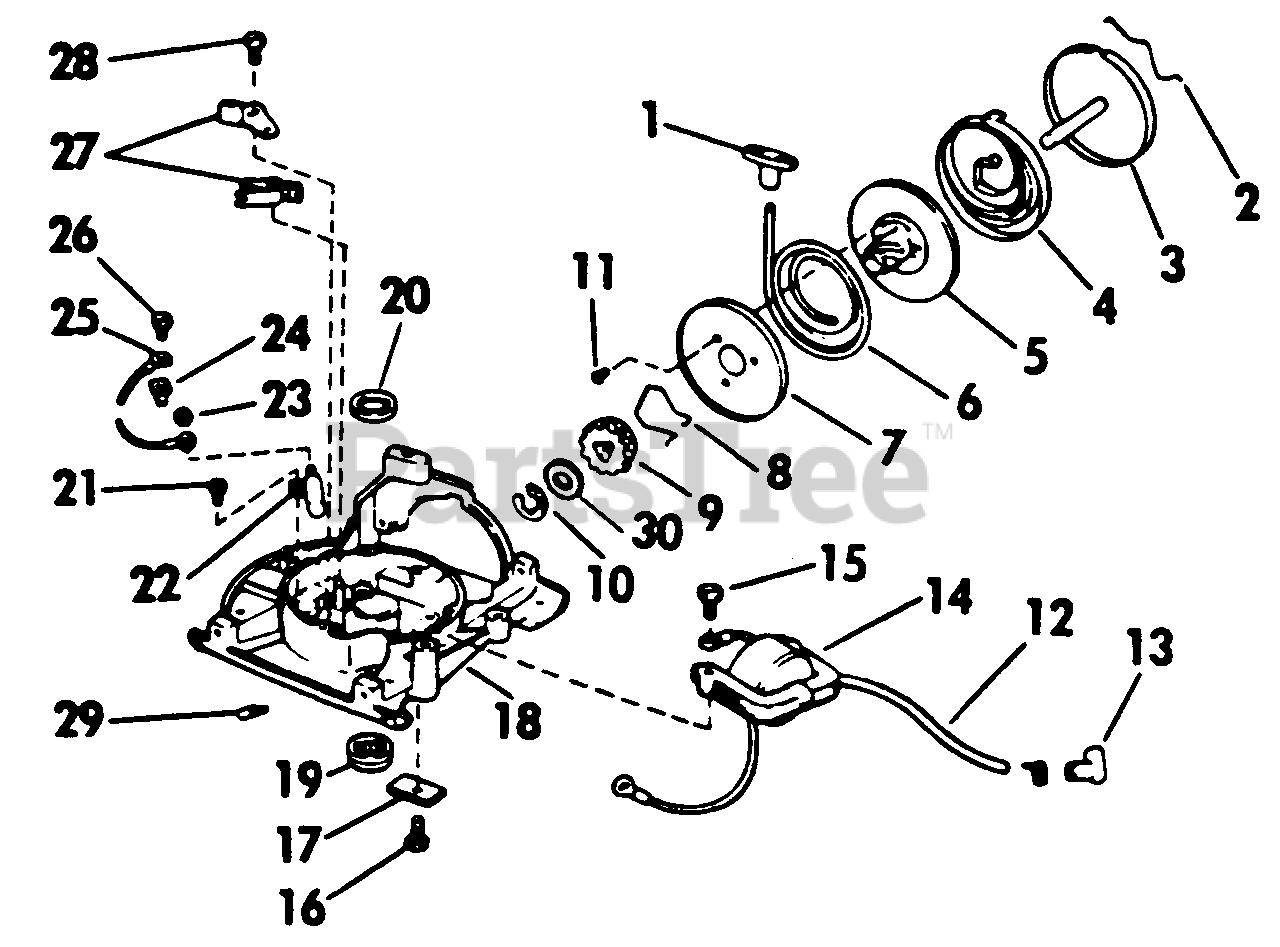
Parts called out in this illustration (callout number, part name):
1	Handle-Starter
2	Spring-Starter Rope Retainer
3	Spring-Cup-Pin Assy.
4	Spring-Starter
5	Pulley-Starter
6	Rope-Starter
7	Plate-Starter Pulley
8	Spring-Starter Pinion
9	Pinion-Starter
10	Retainer-Push-On
11	Screw-Threaded Cutting Starter
12	High Tension Lead Assy.
13	Cover & Terminal Assy.
14	Coil & Lamination Assy.
15	Scr.-Lamination Mtg.
16	Scr.-Starter Attach.
17	Clamp-Starter Pin
18	Arm. Pl., Brg. & Oil Seal Assy.
20	Oil Seal
21	Scr.-Cond. Mtg.
22	Cond. & Nut Assy.
24	Grommet-Nylon
25	Terminal & Lead Assy.
26	Scr.-Shut-Off Sw.
27	Brkr. Base & Arm Assy.
28	Scr.-Breaker Base
